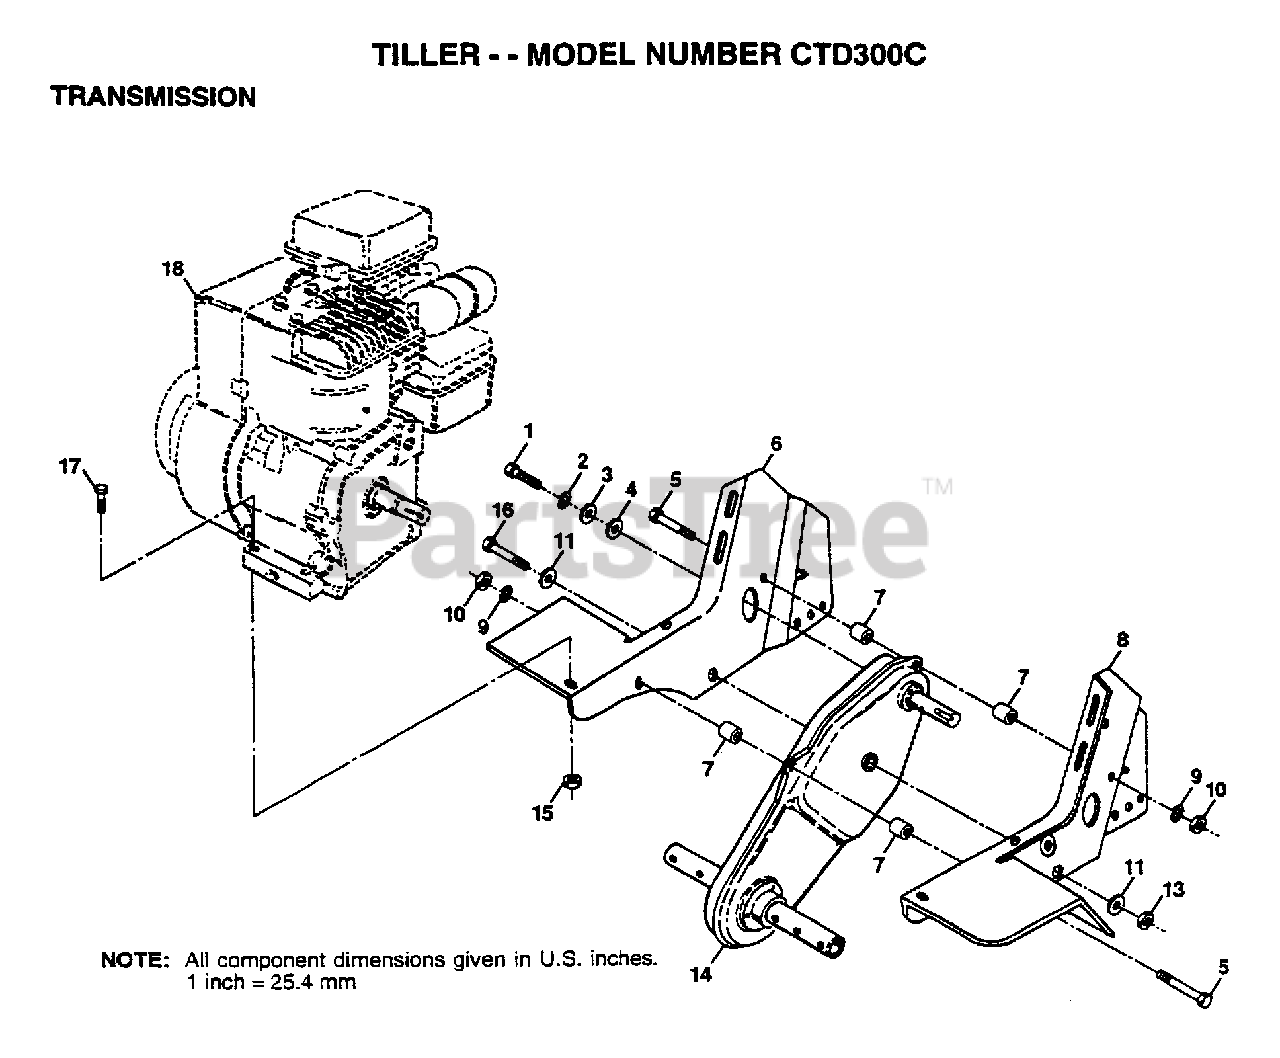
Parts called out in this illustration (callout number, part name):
1	BOLT
2	LOCKWASHER
3	WASHER
4	WASHER
6	BRACKET.ENGINE.RH
7	SPLIT SPACER RT
8	BRACKET.ENGINE.LH
9	LOCKWASHER
10	NUT.HEX.5/16-18
11	WASHER
13	NUT
16	BOLT HEX 3/8-16
17	BOLT.HEX.5/16-1.5
